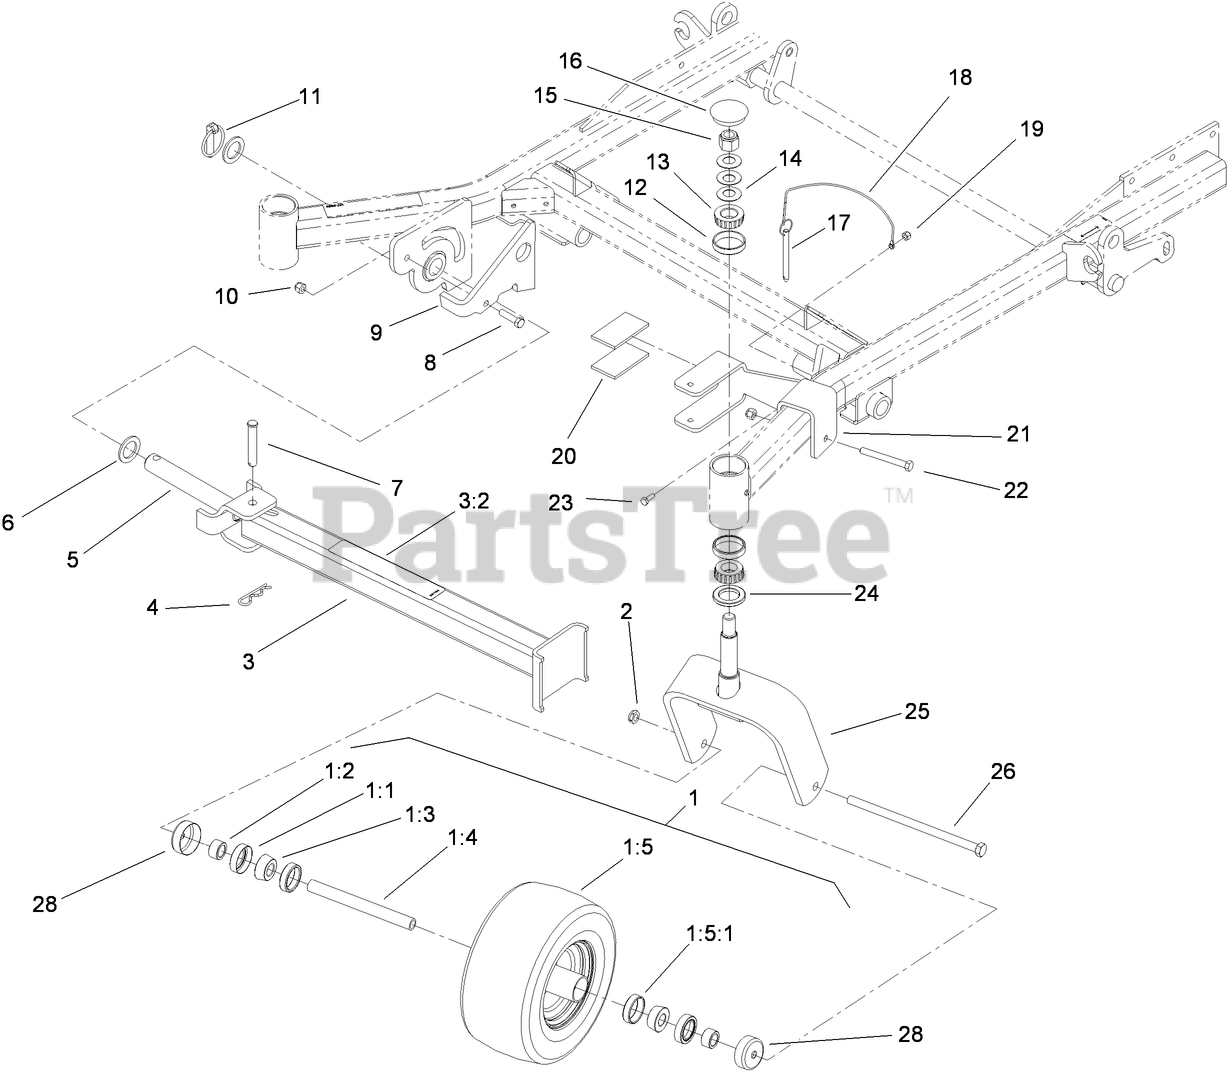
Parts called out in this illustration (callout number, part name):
1	WHEEL AND TIRE ASM
1:1	BEARING-CONE, TAPER
1:2	SEAL-CASTER
1:3	SPACER-NUT
1:4	AXLE-CASTER
1:5	WHEEL AND TIRE ASM
1:5:1	BEARING-CUP
2	NUT-LOCK, NI
3	Leg ASM
3:2	DECAL-Z STAND
4	PIN-HAIR
5	PIN-PIVOT
6	WASHER-THRUST
7	PIN-CLEVIS
8	SCREW-HH
9	BRACKET-LATCH
10	NUT-LOCK, NI
11	PIN-LYNCH
12	BEARING-CUP, TAPERED
13	BEARING-CONE, TAPERED
14	WASHER-BELLVILLE
15	NUT-LOCK, NI
16	CAP-GREASE
17	PIN-HITCH, COTTERLESS
18	LANYARD-NYLON
19	NUT-LOCK, NI
20	Cushion-Rubber
21	BRACKET-CRADLE
22	SCREW-HH
23	SCREW-HH
24	SEAL-GREASE
25	CASTER-FORK
26	Screw-HH
28	GUARD-SEAL
